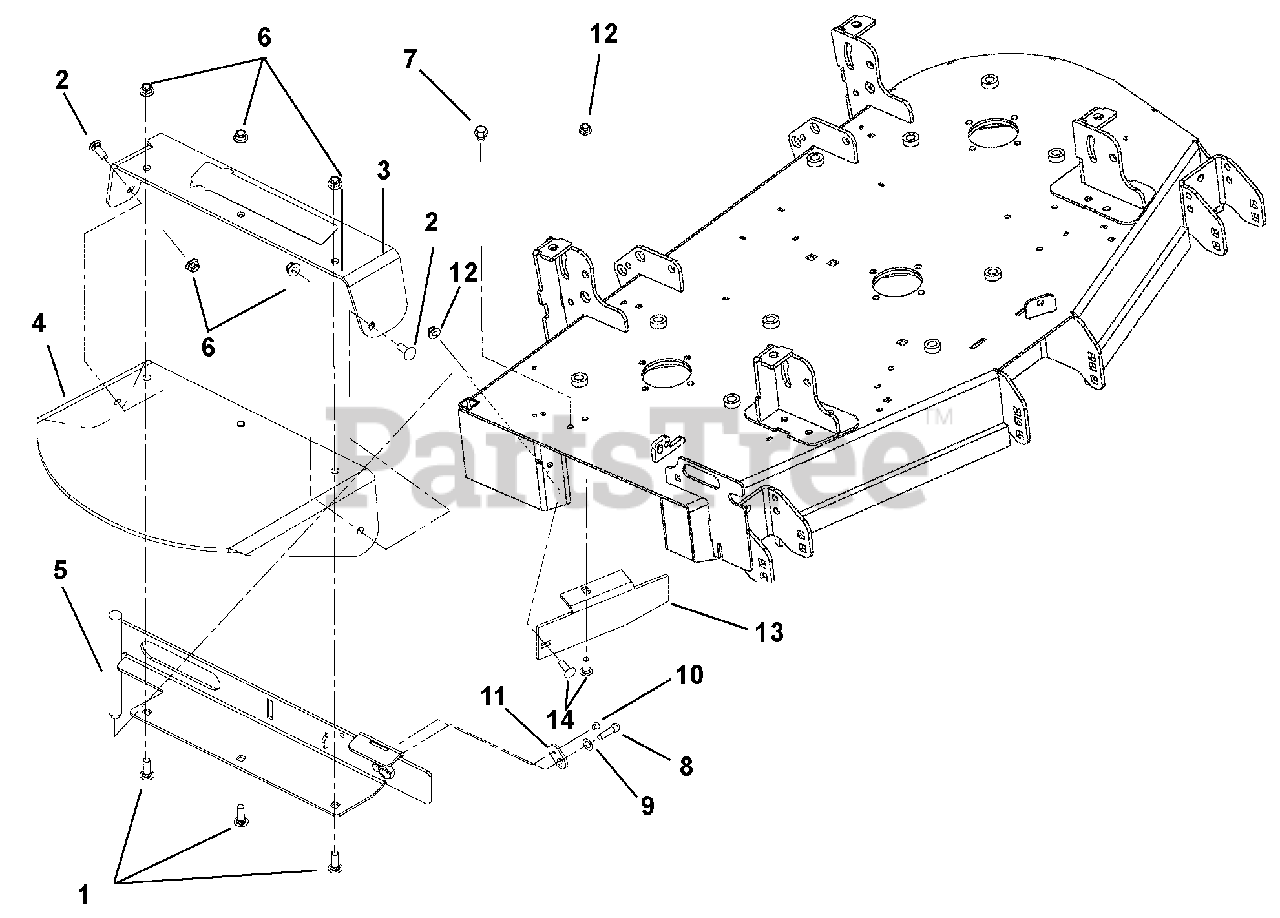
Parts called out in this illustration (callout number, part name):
1	Bolt, Round Head Square Neck .38 - 16 x 1.25
2	Bolt, Round Head Square Neck .38 - 16 x 1.00
3	Rubber Discharge Chute Support
4	Chute, Rubber Discharge
5	Weldment, 48" Discharge Chute Mounting, CE
6	Nut, Locking, Nylon, Flange .38 - 16
7	Screw, Self Tapping .38 - 16 x .50
8	Bolt, Hex .38-16 x 1.25
9	Washer, Locking, EXT.391 x .682 x .036
10	Rivet, Pop .187
11	Keeper, Bolt
12	Nut, Locking Nyloc Flange .31 - 18
13	Discharge Baffle
14	Bolt, Round Head Square Neck .31 - 18 x 1.00
